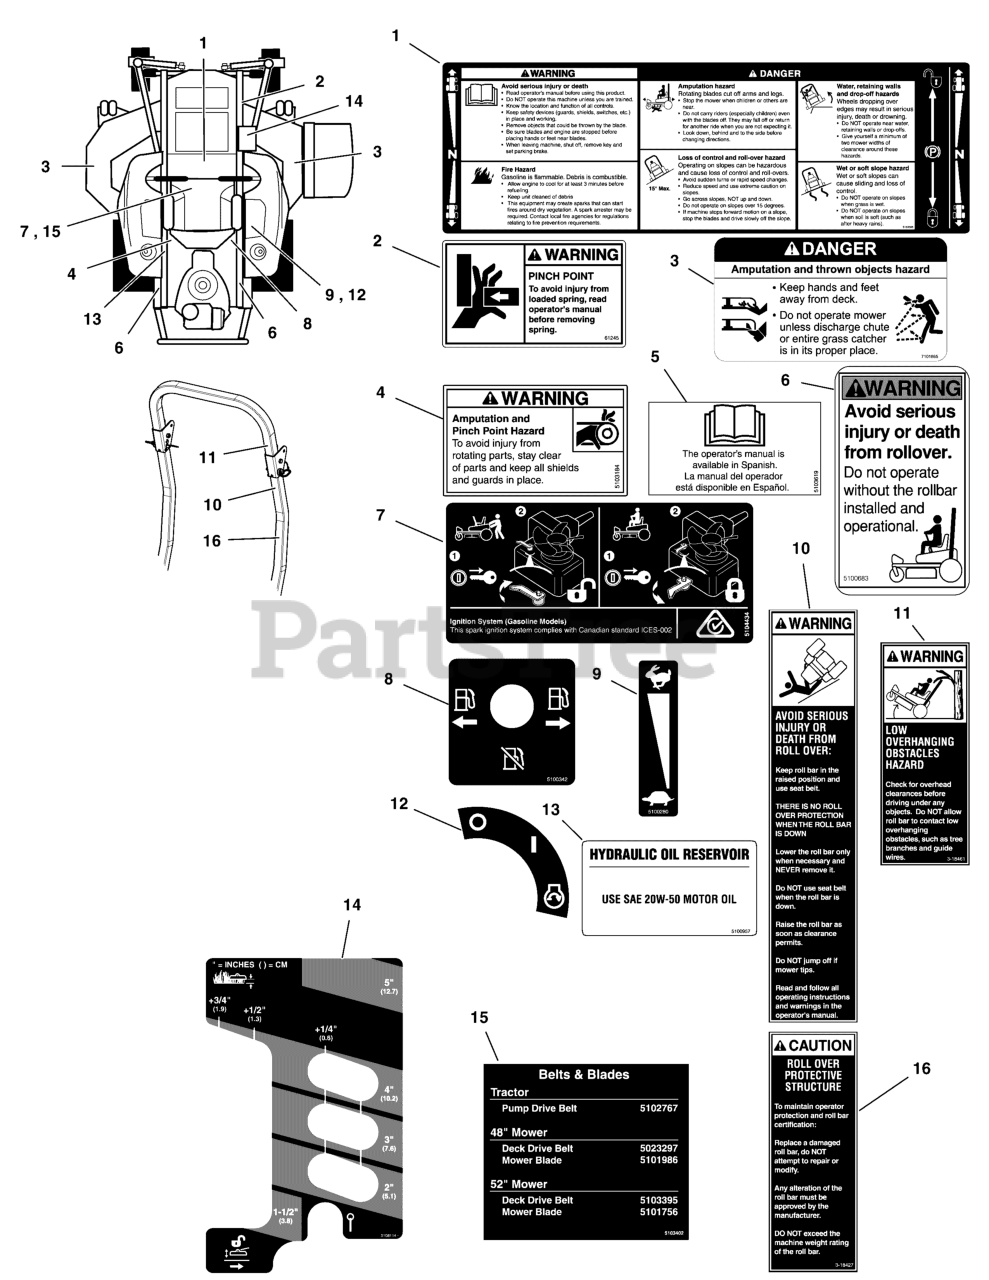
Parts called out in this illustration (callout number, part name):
1	DECAL, MAIN SAFETY
2	DECAL, PINCH POINT
3	DECAL, DANGER DO NOT OPERATE W/O DEFLECT
4	DECAL, WARNING, HAND IN BELT, ENG ONLY
5	DECAL, MANUAL AVAIL IN SPANISH
6	DECAL, WARNING, ROLL BAR
7	DECAL, TRANSAXLE RELEASE, ZT4400
8	DECAL, FUEL VALVE
9	DECAL, THROTTLE CONTROL
10	DECAL, WARNING, FLDG ROPS
11	DECAL, WARNING OVERHANG, ROPS
12	DECAL, IGNITION SWITCH
13	DECAL, HYDRAULIC OIL, SAE 20W50
14	DECAL, CUT HEIGHT, S150XT
15	DECAL, BELT & BLADE, S150XT
16	DECAL, CAUTION, FLDG ROPS
